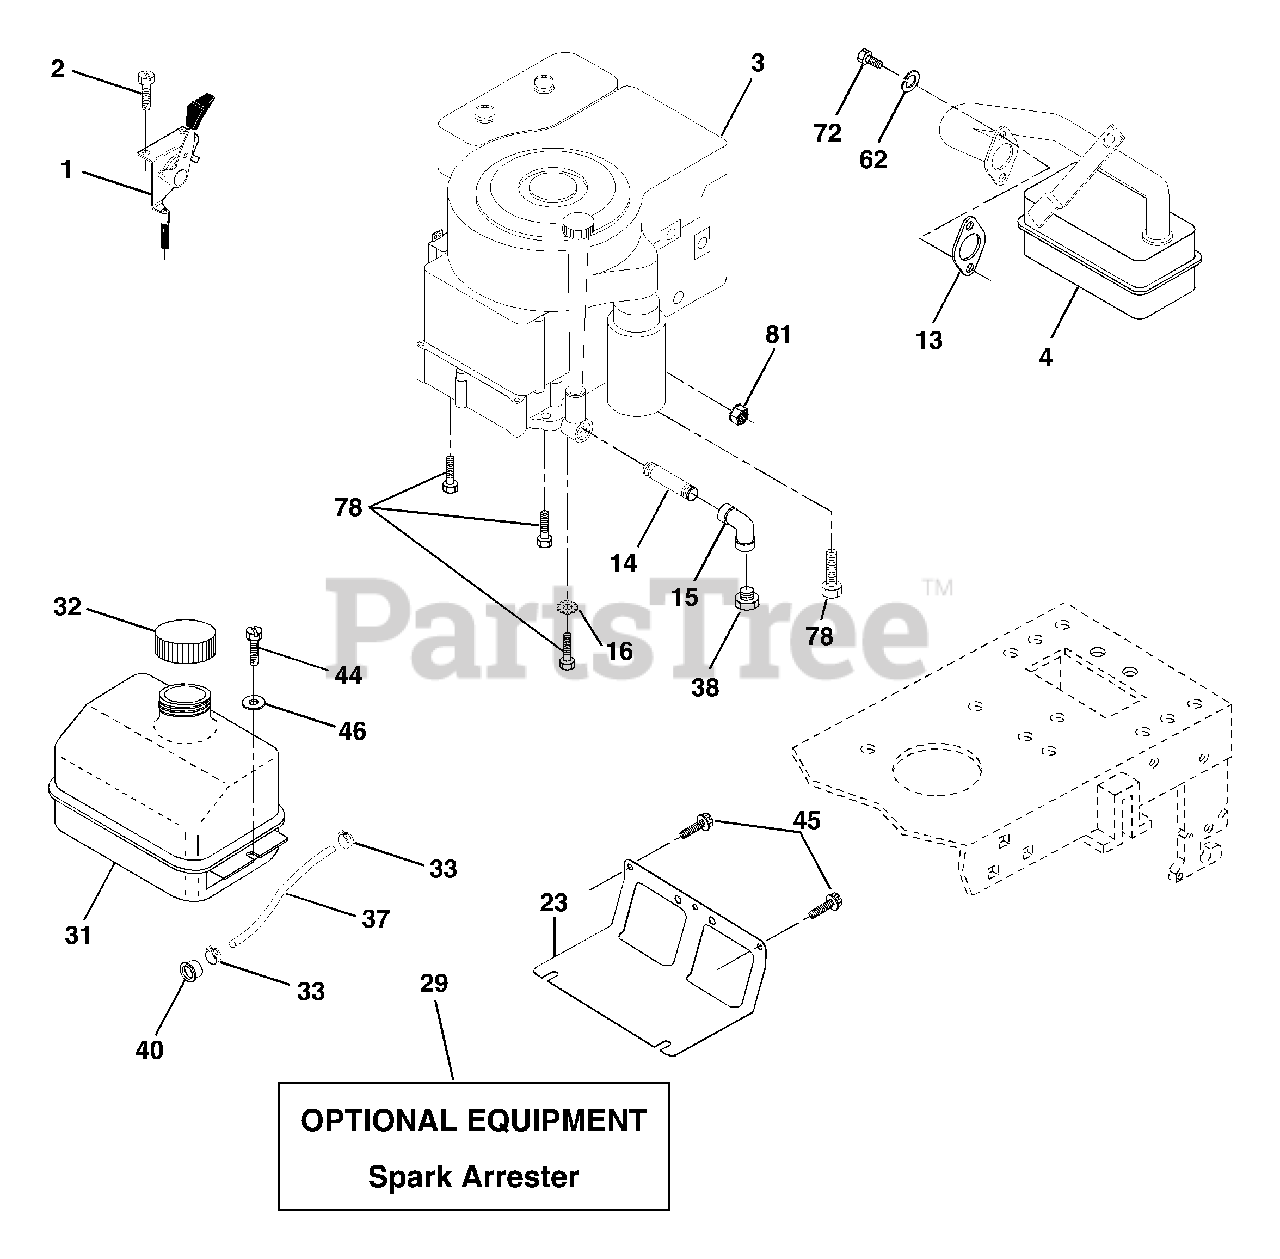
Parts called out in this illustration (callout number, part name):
1	Control Th/ch Flag
2	Screw Hex Thd Cut 1/4-20 x 1/2
4	Muffler Exhaust B&S
13	Gasket Eng 1 313 Id Tin Plated
14	Nipple Pipe 3/8 Npt x 3"
15	Elbow Std 90 Degree 3/8-18 Npt
16	Washer Lock Ext Tooth 3/8
23	Shield BRN/DBR Guard
29	Kit Spark Arrestor (Flat Scrn)
31	Tank Fuel Front
32	Cap Asm Fuel
33	Clamp Hose
37	Line Fuel 20"
38	Oil Drain Plug
40	Bushing Snap Nyl Blk Fuel Line
44	Screw Thdrol 1/4-20 x 3/4
45	Screw Hex Wsh Thdrol 3/8-16
46	Washer 9/32 X 7/8 X 16 Ga
62	Washer Lock Hvy Hlcl Spr
72	Screw Hexcap 5/16-18 x 3/4
78	Screw 3/8-16 x 1-1/4
81	Nut Keps Hex 1/4-20 Unc
